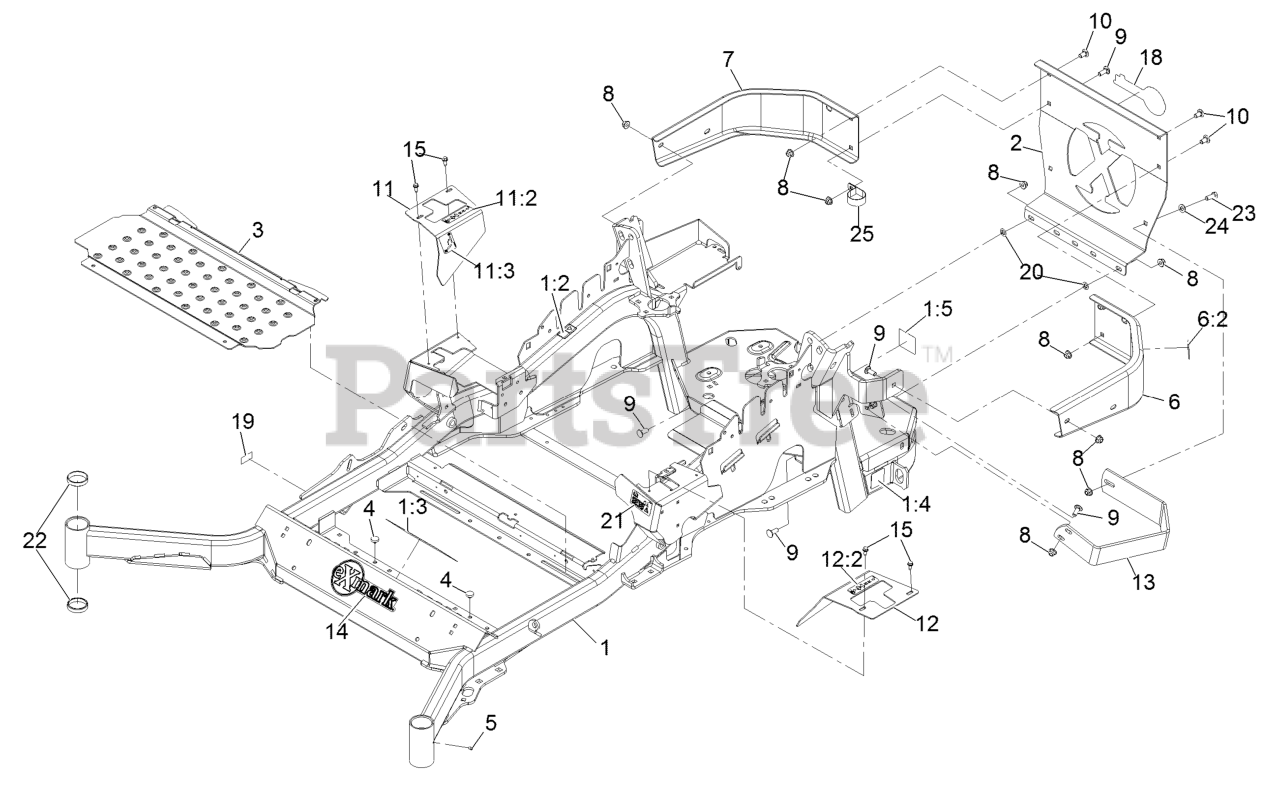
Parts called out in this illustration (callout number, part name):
1	MAINFRAME ASM
1:2	DECAL-WARNING
1:3	DECAL-DANGER
1:4	DECAL-HAZARD, PINCHED FINGER
1:5	DECAL-SPARK ARRESTER
2	PLATE,REAR GUARD
6	LH BUMPER ASM
6:2	DECAL-WARNING
7	BUMPER-RH
8	NUT-HF, NI
9	SCREW-CARR
10	SCREW-CARR
11	RH MOTION CONTROL COVER ASM
11:2	DECAL-CONTROL, MOTION
11:3	DECAL-PARK BRAKE, CE
12	LH MOTION CONTROL COVER ASM
12:2	DECAL-CONTROL, MOTION
13	GUARD-MUFFLER
14	DECAL-EXMARK LOGO
15	SCREW-HWH
18	DECAL-EXMARK LOGO
19	Decal-Patent
20	NUT-PUSH
21	DECAL-FUEL FILL, CE
22	CUP-BEARING
23	SCREW-HH
24	WASHER-FLAT
25	CLAMP-R
